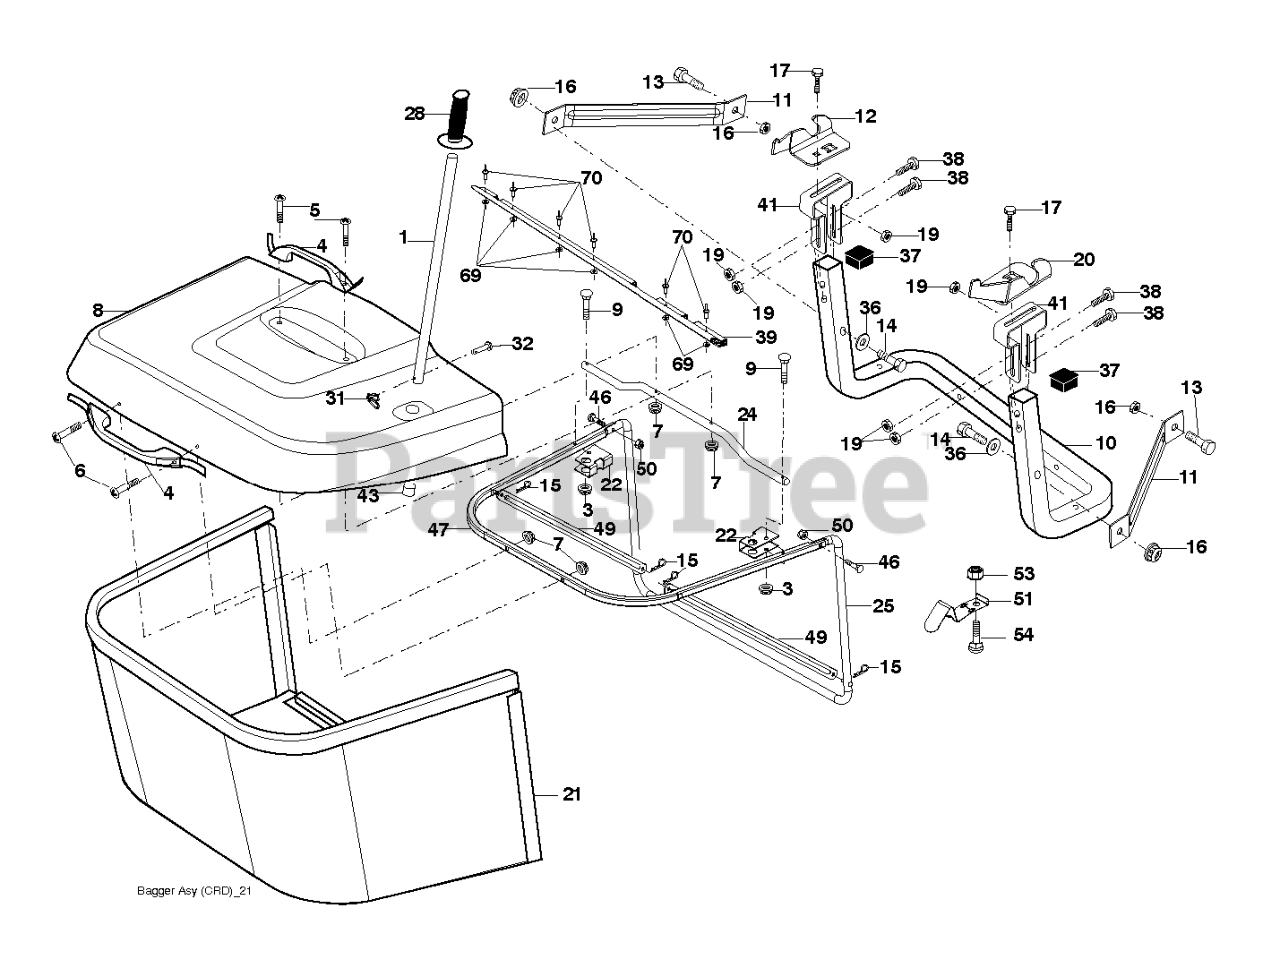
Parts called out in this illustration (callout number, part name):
1	TUBE.HANDLE.BAGGER.CRD/SRD.BLA
3	NUT T
4	HANDLE.BAGGER.W/LVRS.BLK.CRD
5	SCREW.PAN.HEAD
6	REPL BY 532 75 00-29
8	COVER.PNT.BGR.CRD.WSLOTS.MS668
9	Bolt Carriage 1/4-20 x 2.25d x Gr.5
10	TUBE
11	BRACKET.SUPPORT.UPPER.BAG.CRD
12	BRKT PIVOT
14	BOLT-HEX EAK
15	RETAINER-SPRNG RB
16	NUT LOCK FLG 3/8-16 UNC
17	RP BOLT 5/16-18 X3/4 ZN/YEL GR
19	NUT LOCK HEX FLANGE 5/16-18
20	BRKT.PIVOT.RH.CRD
21	BAGGER.ASM.CRD.2007
22	BRACKET.BAGGER.SD.ELECTRIC.CRD
24	TUBE.PIVOT.BAG.CRD.BLACK
25	PIPE
28	GRIP.HANDLE.BLACK
31	RETAINER CLIP
32	RIVET,DRILLED
36	WASHER
37	Plug Support Bagger CRD
38	BOLT.5/16-18X2.5
39	SEAL.BAGGER.CRD
41	BRACKET.BAGGER.SD.ELECTRIC.CRD
43	PLUG, TUBING END
46	BOLT.CARRIAGE.5/16-18
47	PIPE
49	ROD
50	NUT.71038.31-18.HEX.NYLOCK
51	LATCH
53	NUT
54	BOLT
69	WASHER
70	RIVET RIVET POP
